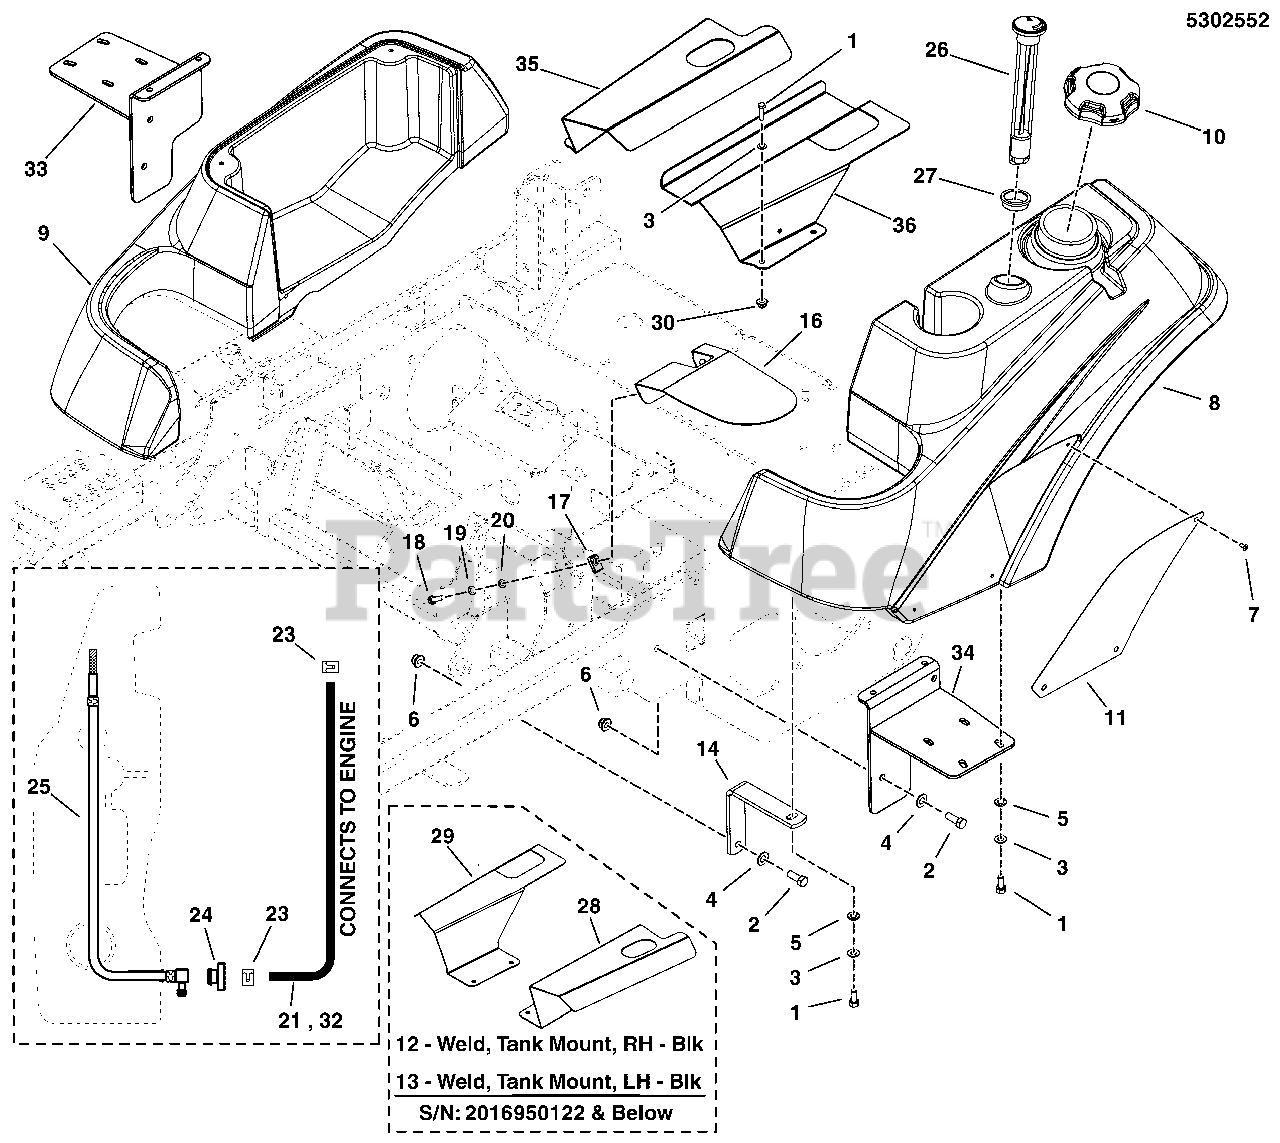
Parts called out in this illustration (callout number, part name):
1	BOLT, 5/16-18 X 3/4 GD5
2	BOLT, 3/8-16 X 1 GD5 YZ
3	WASHER, 5/16" SAE
4	WASHER, 3/8 SAE
5	WASHER, 5/16 LOCK YZ
6	NUT, 3/8-16 HEX NYLOCK FLANGE
7	SCREW, #10-24 X 3/8 ALLEN BHBZ
8	TANK, FUEL, LH, 1500Z
9	TANK, FENDER, CITATION/ZT4000 - RH
10	FUEL CAP, 3-1/2", MANAGED VENT OUT, 12"
11	BADGE, IS1500Z, RED
12	WELD, TANK MOUNT, RH - RED
13	WELD, TANK MOUNT, LH - RED
14	BAR, TANK MOUNT, FRONT - RED
16	GUARD, MOTION CONTROLS, LH - BLK
17	BODY CLIP, 1/4-20 X 1/2 DEEP
18	BOLT, 1/4-20 X 1" GD5 CZ
19	WASHER, 1/4 SAE (5025154)
20	WASHER, 1/4 LOCK
21	HOSE, 1/4" FUEL, 14.00"
23	CLAMP, HOSE, EXTERNAL, 1/2 - RED
24	BUSHING-FUEL TANK RED RUBBER (SV)
25	PICKUP TUBE ASM, FUEL TANK
26	GAUGE, FUEL, 12
27	GROMMET, FUEL GAUGE
28	GUARD, FUEL MOUNT, LH - RED
29	GUARD, FUEL MOUNT, RH - RED
30	NUT, 5/16-18 HEX NYLOCK FLANGE
32	HOSE, 1/4" FUEL, 37.00"
33	WELD, TANK MOUNT, F200XT, RH - BLK
34	WELD, TANK MOUNT, F200XT, LH - BLK
35	GUARD, FUEL MOUNT, F200XT, RH - BLK
36	GUARD, FUEL MOUNT, F200XT, LH - BLK
